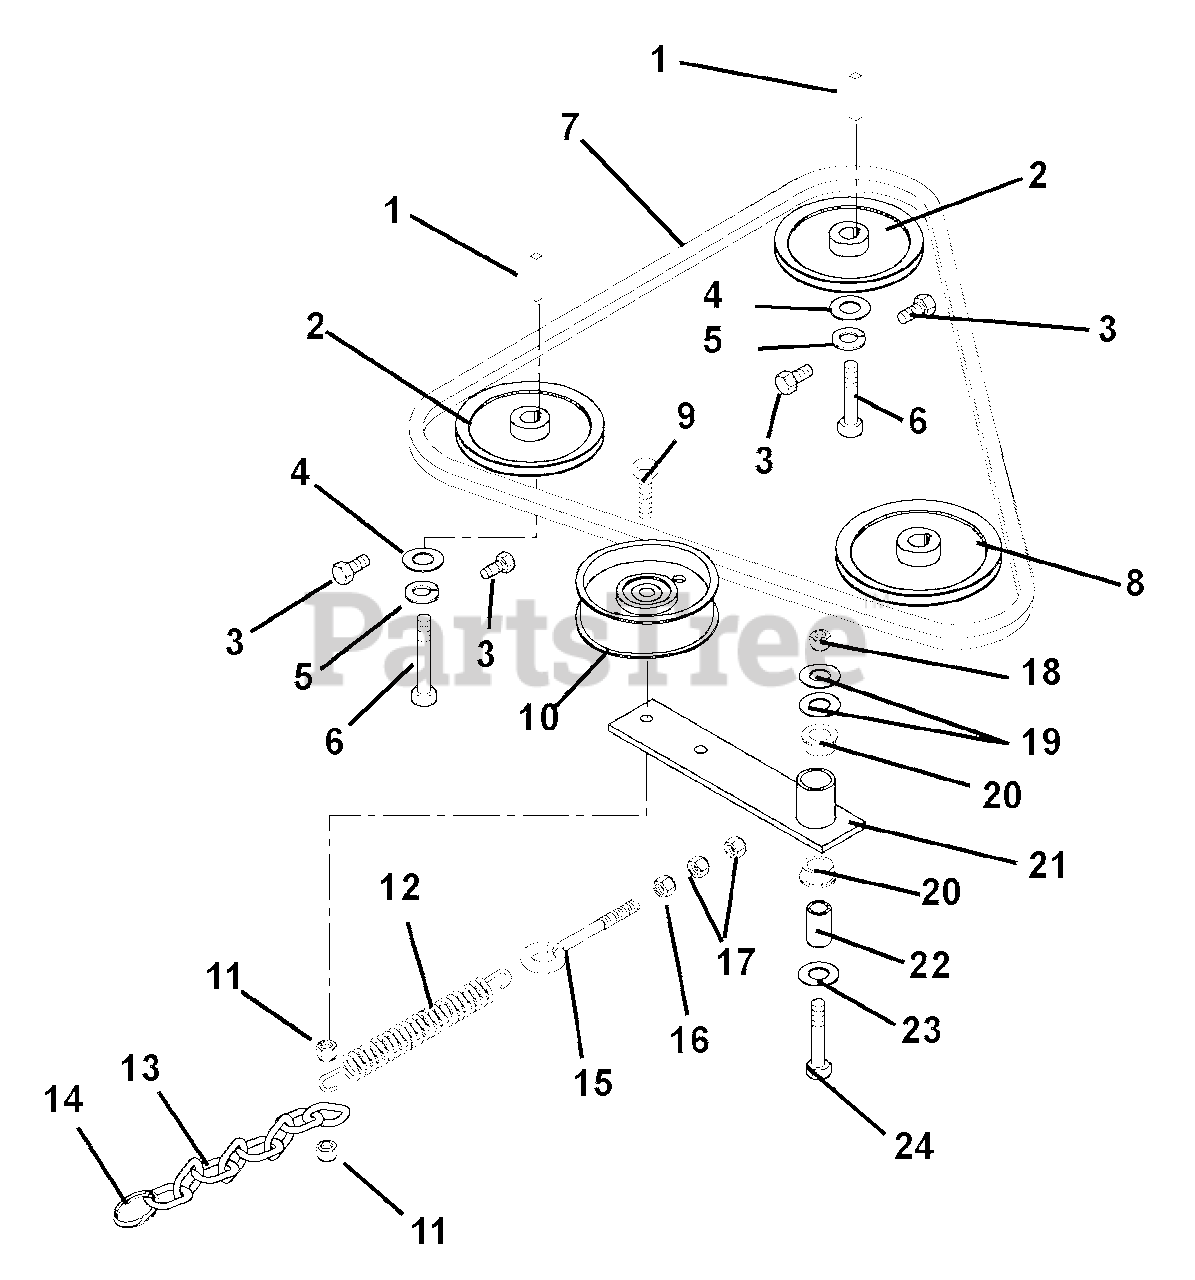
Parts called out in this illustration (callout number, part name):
1	KEY-STR 5MMX25MMX5MM
2	SHEAVE, PUMP .592 X 4.345
3	@BLT-HEX .25-20X.50 GR5 YWZC
4	WSHR-FL-STL .281X1.250X.048PL
5	@WSHR-LK .25X.062 REG YWZC
6	BLT-HEX M6 X 1.0X12 YWZC
7	V-BELT, 4L-RAW EDGE
9	@BLT-HEX .38-16X2.00 GR5 YWZC
10	IDLER-PLY FLAT 3.25 X .38 X1.0
11	@NUT-LK-CTR-JAM .375-16 YWZC
12	SPRING, EXT
13	CHAIN, LINK
14	RING, SPLIT .1 X 2
15	BLT-EYE .375-16X2.50 YWZC
16	@NUT-HEX .38-16 YWZC
17	@NUT-LK-NYL .38-16 YWZC
18	@NUT-LK-NYL .50-13 YWZC
19	@WSHR-FL-STL.531X1.06X.095YWZC
20	BSHG-FLG .762X1.0X.580X1.48 NY
21	WLDMT,GROUND DRIVE IDLER
22	BUSH.,S.560X.745X2.04 ST
23	@WSHR-FL-STL.531X1.06X.095YWZC
24	@BLT-HEX .50-13X3.25 GR5 YWZC
